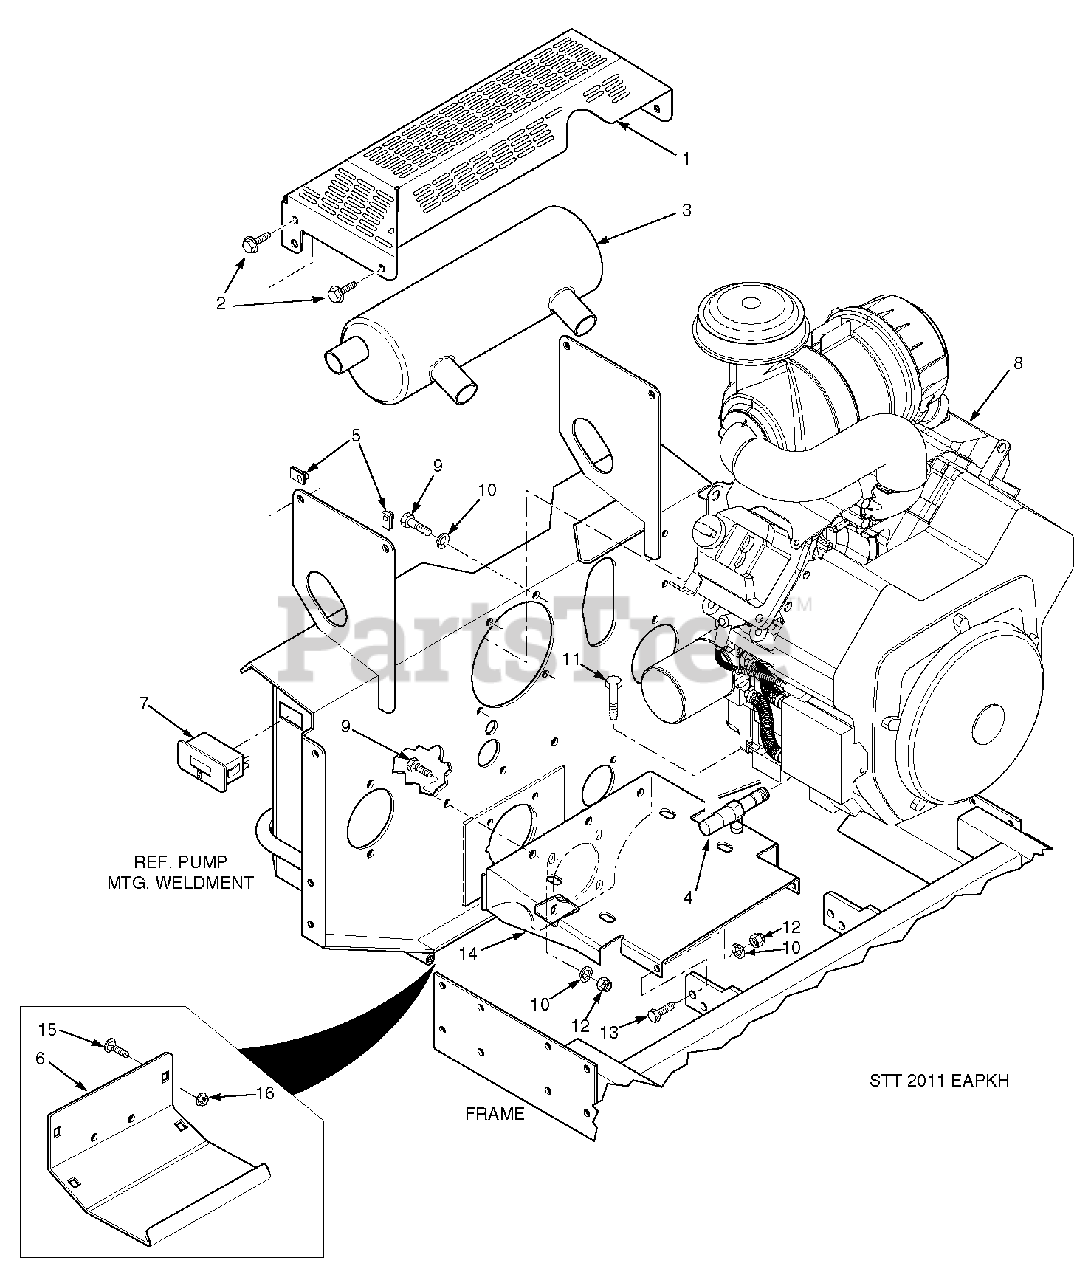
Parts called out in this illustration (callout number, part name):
1	Muffler Guard
2	Screw, Hex Serrated Flange 1/4-20 x 3/4"
3	Muffler, Part Of Engine
4	Oil Drain Extension
5	U-Nut, 1/4-20
6	Rear Cover
7	Hour Meter
8	Engine
9	Bolt, Hex Head 3/8-16 x 1"
10	Lockwasher, 3/8" Spring
11	Bolt, Hex Head 3/8-16 x 1-3/4"
12	Nut, Hex Elastic Stop 3/8-16
13	Bolt, Hex Head 3/8-16 x 1-1/4"
14	Plate, Engine Mounting
15	Bolt, Carriage 5/16-18 x 3/4"
16	Nut, Hex Serrated Flange 5/16-18
